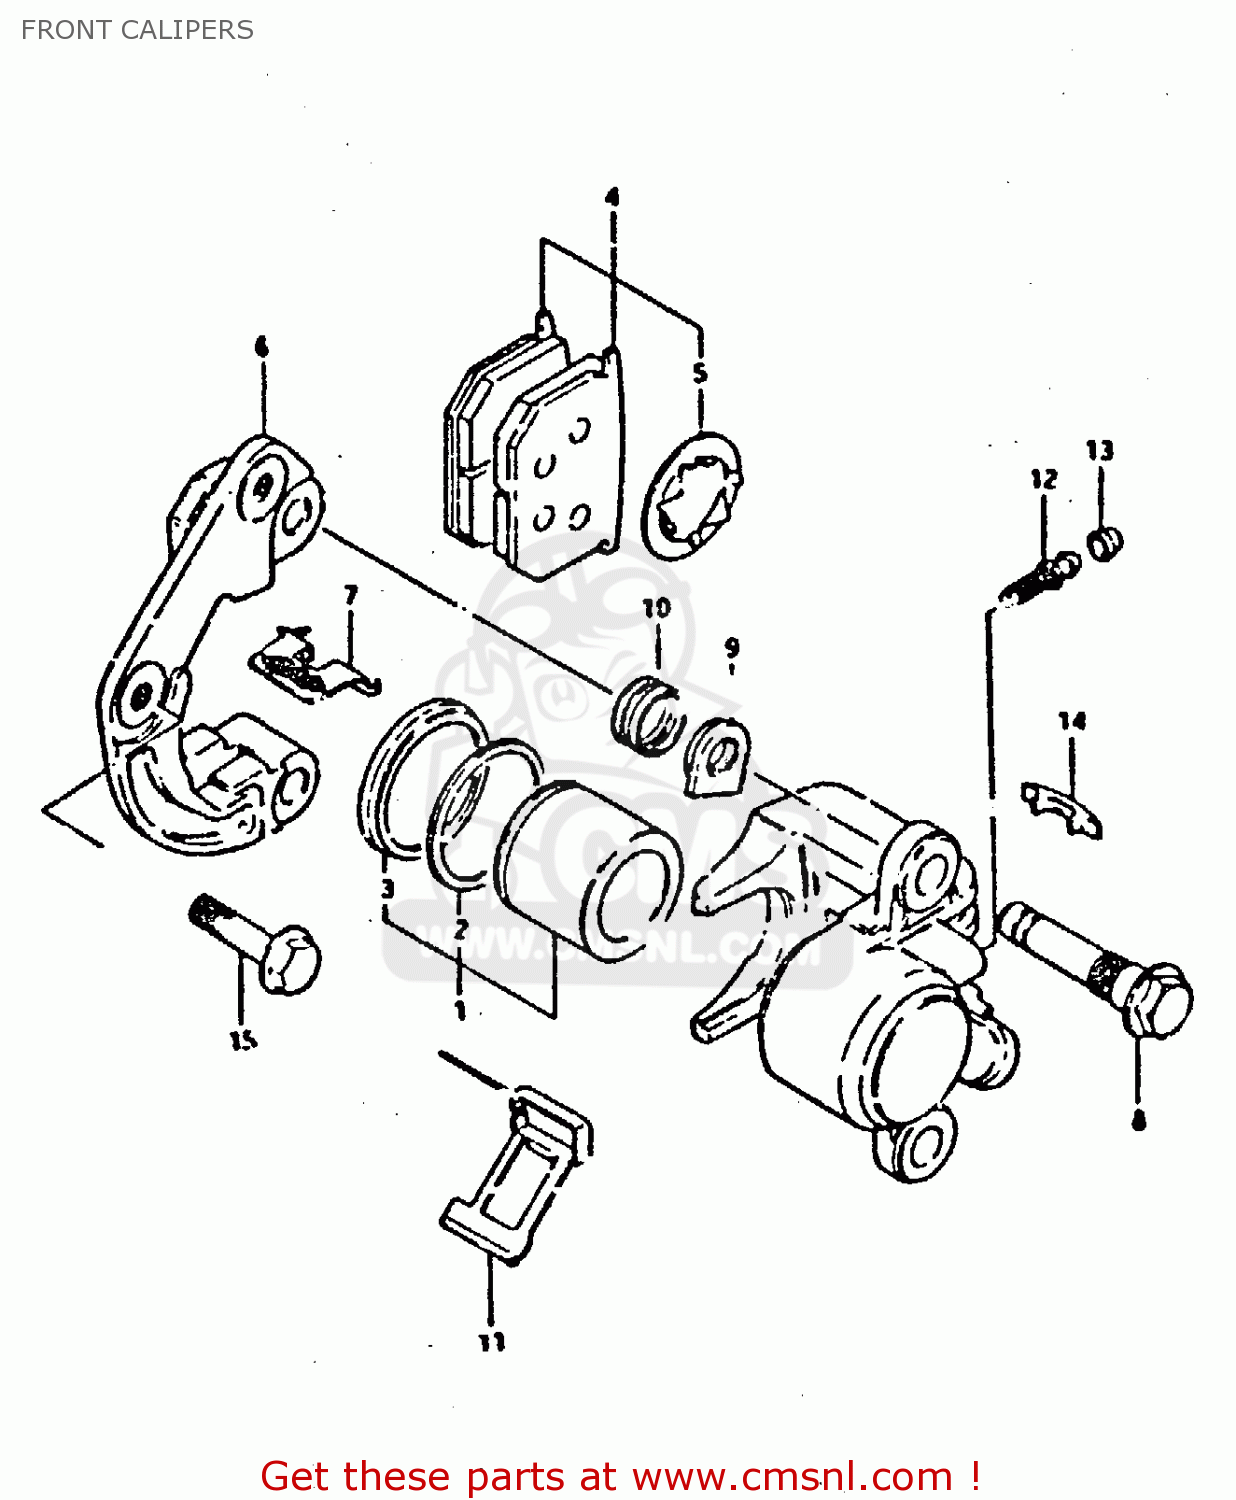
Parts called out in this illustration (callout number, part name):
1	PISTON SET
2	SEAL,PISTON
3	BOOT,PISTON
4	PAD & SHIM SET (MCA)
5	SHIM,PAD
6	HOLDER,CALIPER,LEFT
7	PAD,GUIDE
8	AXLE
9	NUT,CALIPER AXLE
10	BOOT
11	SPRING
12	BREADER
13	CAP,BLEEDER PL
14	COVER,INDICATOR
15	BOLT
